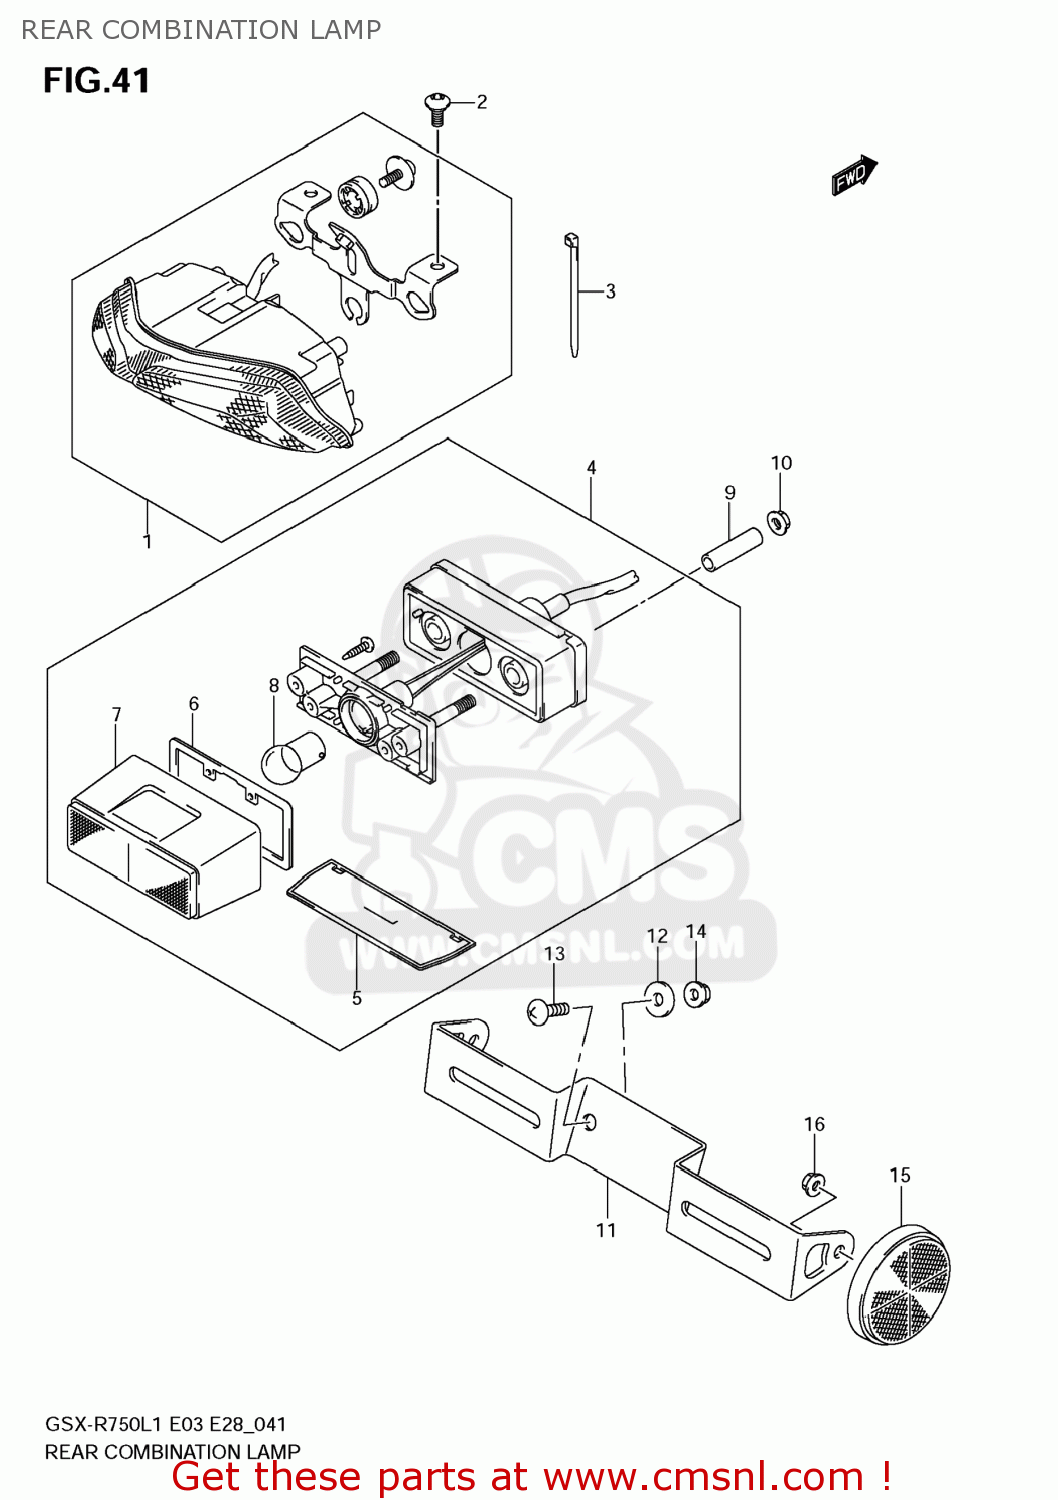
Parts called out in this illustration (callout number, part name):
1	LAMP ASSY,RR COMBINATION
2	BOLT(5X13)
3	CLAMP(L:100)
4	LAMP ASSY,LICE
5	LENS LICENCE
6	GASKET (NAS)
7	COVER,LICENSE LAMP
8	BULB(12V5W,BF150-40160A)
9	SPACER(6.5X9X34)
10	NUT
11	BRACKET,LICENSE PLATE
12	WASHER(6.5X20X1.2)
13	SCREW
14	NUT
15	REFLECTOR ASSY,RR SIDE
16	NUT
